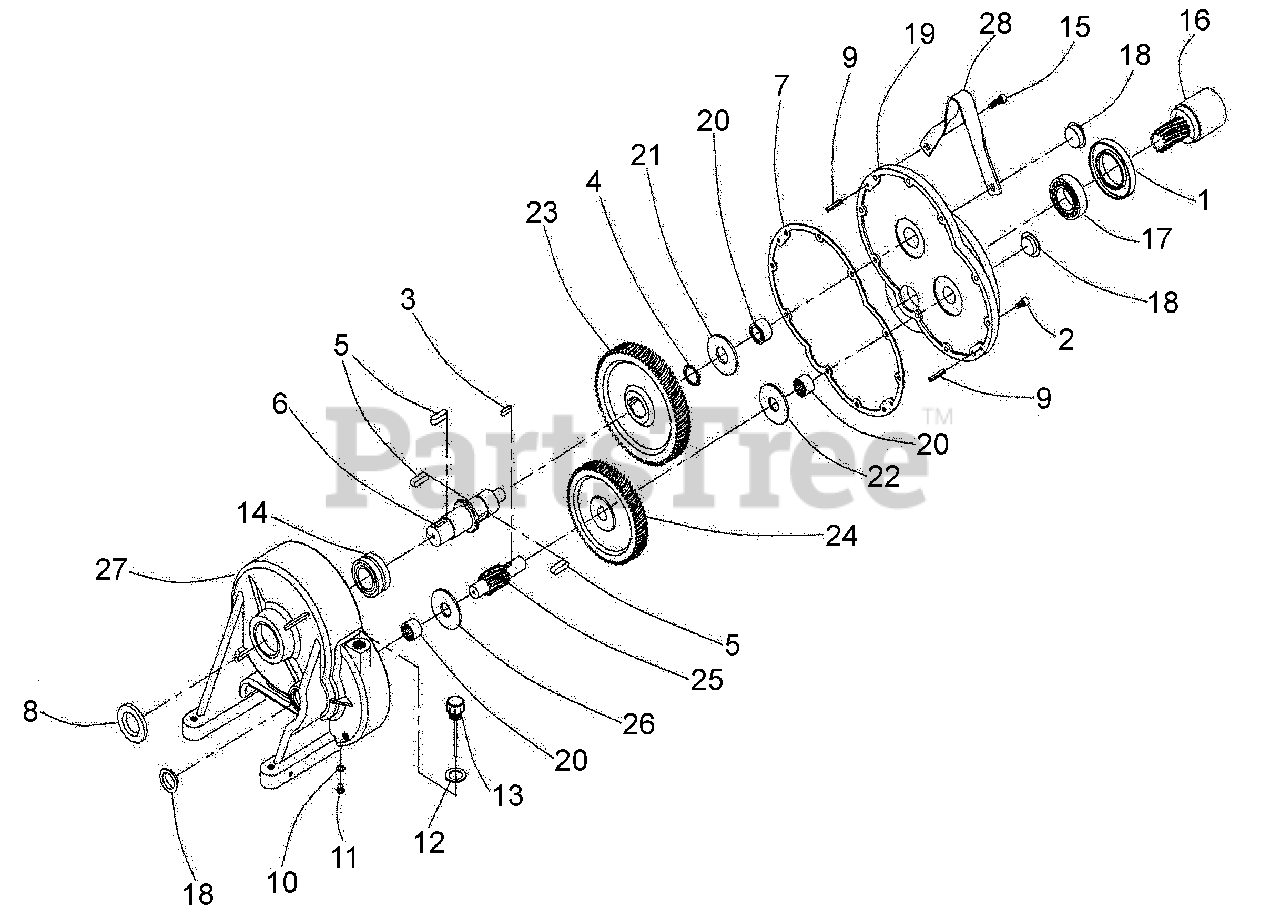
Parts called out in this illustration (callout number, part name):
1	SEAL (48X80X10)
2	AHCS (6M-1.0-25M)
7	GASKET, GEAR BOX
12	GASKET, DIPSTICK
13	DIPSTICK, OIL W/DISCHARGE VALVE
14	BEARING, NEEDLE
15	AHCS (6M-1.0)
16	PINION (HELICAL 1:43)
17	BEARING, PINION
19	COVER, GEAR BOX (PINION SIDE)
20	BEARING, NEEDLE
21	WASHER, FIBER
22	WASHER, FIBER
23	GEAR, DRIVEN (1:43 HELICAL)
24	GEAR, DRIVE (1:43 HELICAL) (PINION)
25	SHAFT (1:43 W/HELICAL TEETH)
26	WASHER, FIBER
27	CASE, GEAR BOX ALUMINUM (2D/3D)
28	BAIL, LIFTING *NH1* (BLACK)
